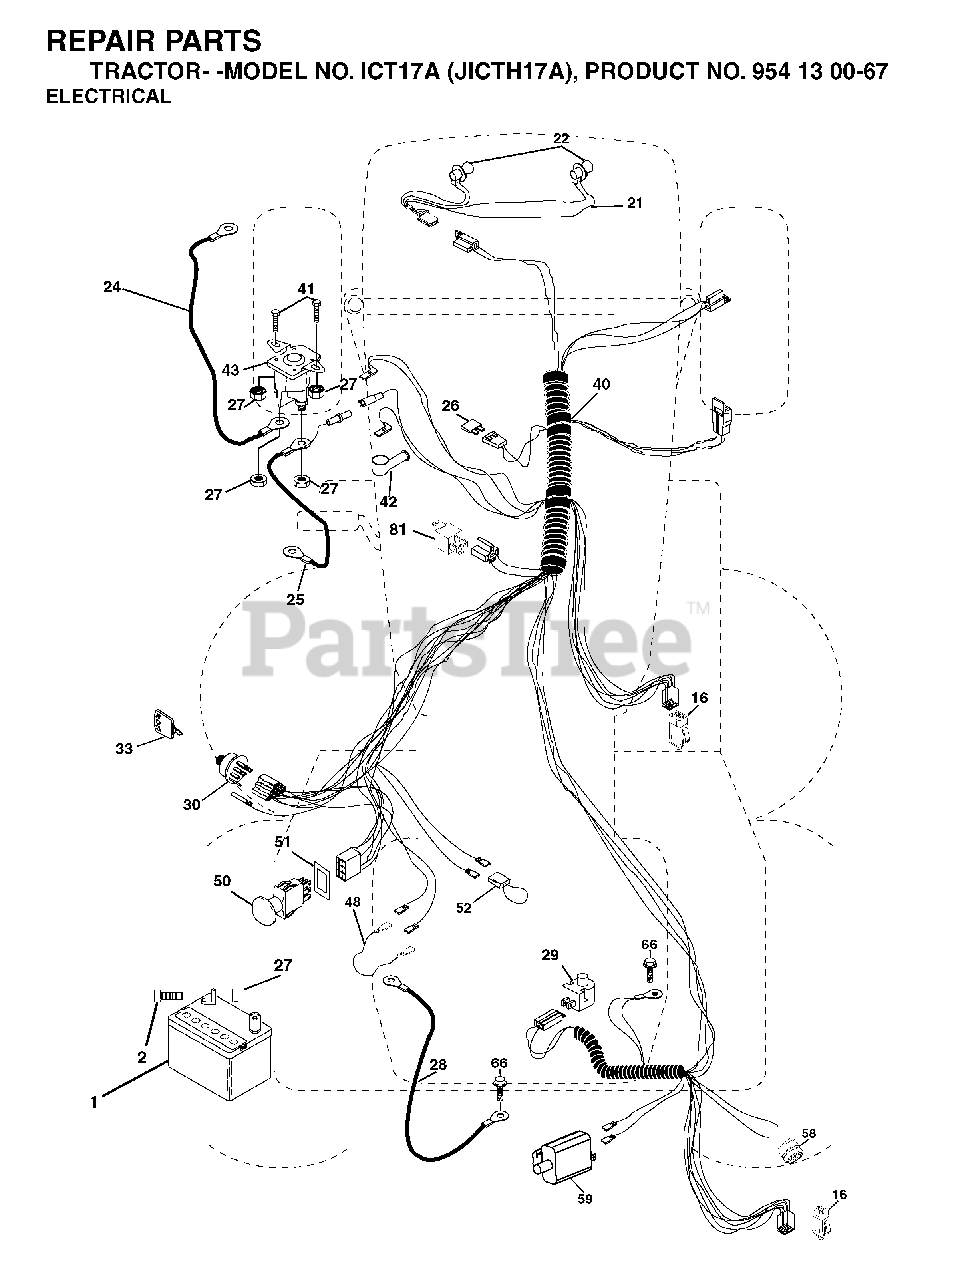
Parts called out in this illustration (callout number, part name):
1	REPL BY 532 12 38-99
16	SWITCH INTERLOOK PUSH-IN
21	HARNESS.W/LIGHT SOCKET
22	LIGHTBULB
24	BATTERY CABLE GT
25	CABLE BATTERY
26	FUSE 20AMP
27	NUT
28	CABLE GROUND
29	PLUNGER SWITCH (COLOR:OLIVE)
30	IGNITION SWITCH
33	KEY MLD GEN DELTA
42	TERMINAL COVER
43	SOLENOID
50	PTO SWITCH
51	RETAINING RING
52	WIRE PROTECTION LOOP
58	BUZZER
81	RELAY.ASSY.T
